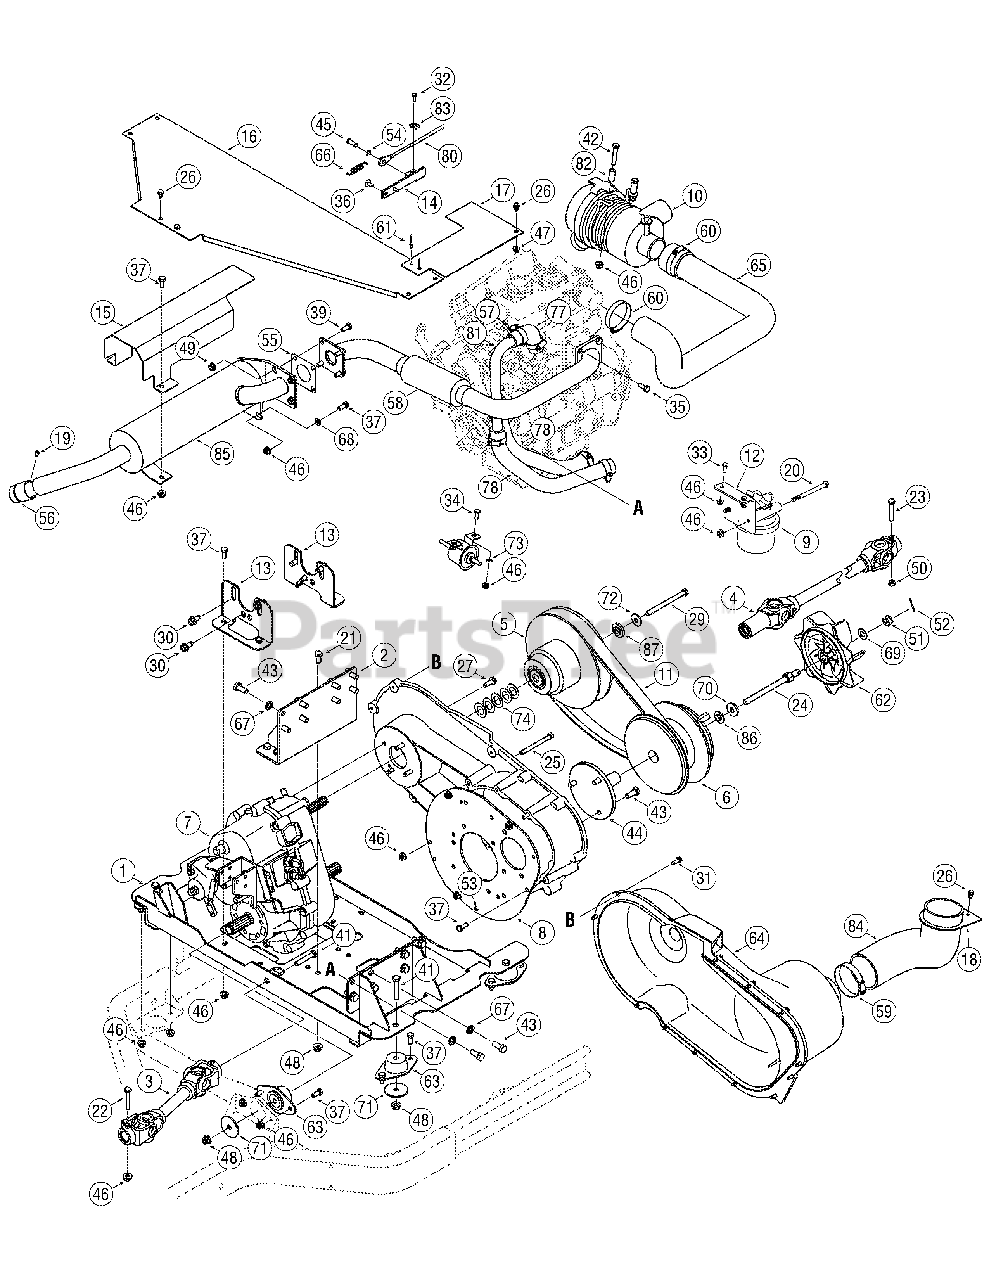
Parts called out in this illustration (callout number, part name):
4	Shf Asm, Frt/prop, Hilliard
5	Clu Asm, Cvt, Driven
6	Clu Asm, Cvt, Driver, Cvr
7	Case Asm, Transfer
8	Hsg Asm, Cvt, Cat; mach
9	Fltr Asm, Diesel
10	Fltr Asm, Aircl, Cat
11	Belt, Cvt
16	Plt, Heat, Shield, Cat
17	Plt, Heat, Shield, Cat
19	Scr, F, #8-32, 0.375, Hxindwsh
20	Hhcs, 5/16-18, 4.00, Gr5, Std
21	Hhcs, 3/8-16, .75, Gr5, Std
22	Hhcs, 5/16-18, 2.00, Gr5, Patch
23	Hhcs, 5/16-18, 1.875, Gr5, Patch
24	Hhcs, 7/16-20, 5.00, Gr5, Special
25	Scr, 5/16-18 X 3.50
26	Scr, Tt, 1/4-20, 0.500, Hxindwsh
27	Scr, Tt, 5/16-18, 1.000, Hxindwsh
28	Scr, B, 5/16-12, 0.500, Hxindwsh
29	Hhcs, 3/8-24, 4.50, Gr5, Std
30	Scr, Tt, 3/8-16, 0.750, Hxindwsh
31	Scr, Tt, 1/4-20, 0.750, Hxindwsh
32	Scr, Sf, #10-24, 0.625, Hxindwsh
33	Scr, Ab, 5/16-12, 0.750, Hxindwsh
34	Hhcs, 1/4-20, .620, Gr5, Std
35	Hhcs, M8-1.25, 20.00, Gr8.8, Std
36	Scr, Torx, M6-1 X 15.00
37	Hhcs, 5/16-18, .75, Gr5, Std
38	Hhcs, 1/4-20, .75, Gr5, Std
39	Hhcs, 5/16-18, .875, Gr5, Std
40	Hhcs, M8-1.25, 16mm, Gr8.8, Std
41	Hhcs, 3/8-16, 2.00, Gr5, Std
42	Hhcs, 5/16-18, 1.75, Gr5, Std
43	Hhcs, M10-1.5, 25mm, Gr5
44	Shf, Output, Cat, Tapered
45	Pin, Clevis, 312 Od X .875
46	Nut, Flglk, 5/16-18, Grf, Nylon
47	Nut, Flglk, 1/4-20, Grf, Nylon
48	Nut, Flglk, 3/8-16, Grf, Nylon
49	Nut, Flglk, 5/16-18, Gr5, Sd Lk
50	Nut, Hexlk, 5/16-18, Grb, Ctrlk
51	Nut, Hex, 1/2-20, Gr5, Slot
52	Pin, Cot, 3/32, 1.0
53	Pin, Roll, .25 X .75
54	Ring, E Type, .313
55	Gskt, Eng
56	Arstr, Scrn, Spark
57	Clamp, Hose, Adj
58	Pipe, Exh, Cat
59	Clamp, Hose, Adj, 2-3/4- 3-3/4
60	Clamp, Hose, Adj 2-3"
61	Riv, Pop, .125 Od, #42
62	Impeller, Blo
63	Mt, Comprs, Eng, Hd
64	Cvr, Cvt
65	Hose, Air Inlet, Cat
66	Spr, Extn, .437 O.d. X 1.328
67	Wash, Lock, 7/16 , Regular Duty
68	Wash, Flat, .330 X .630 X .0635
69	Wash, Flat, .510 X 1.00 X .060
70	Wash, Flat, .450x1.250x.164, Ht
71	Wash, Flat, .38 X 2.00 X .12
72	Wash, Bell, .396 X 1.140 X .095
73	Wash, Lock, 1/4, Int Tooth
74	Wash, Fl, .793x1.368 X.025, Ht
75	Wash, Lock, 5/16 Ext Tooth
76	Wash, Flat, .260 X .720 X .060
77	Hose, Rdtr, Rr
78	Hose, Rdtr, Rr
80	Cbl, Cont, Throt, Cat
83	Clamp, Casing
84	Tube, Cvt, Intake
85	Mflr, Cat/khlr
86	Spcr., Shldr.
87	Spcr., Shldr.
